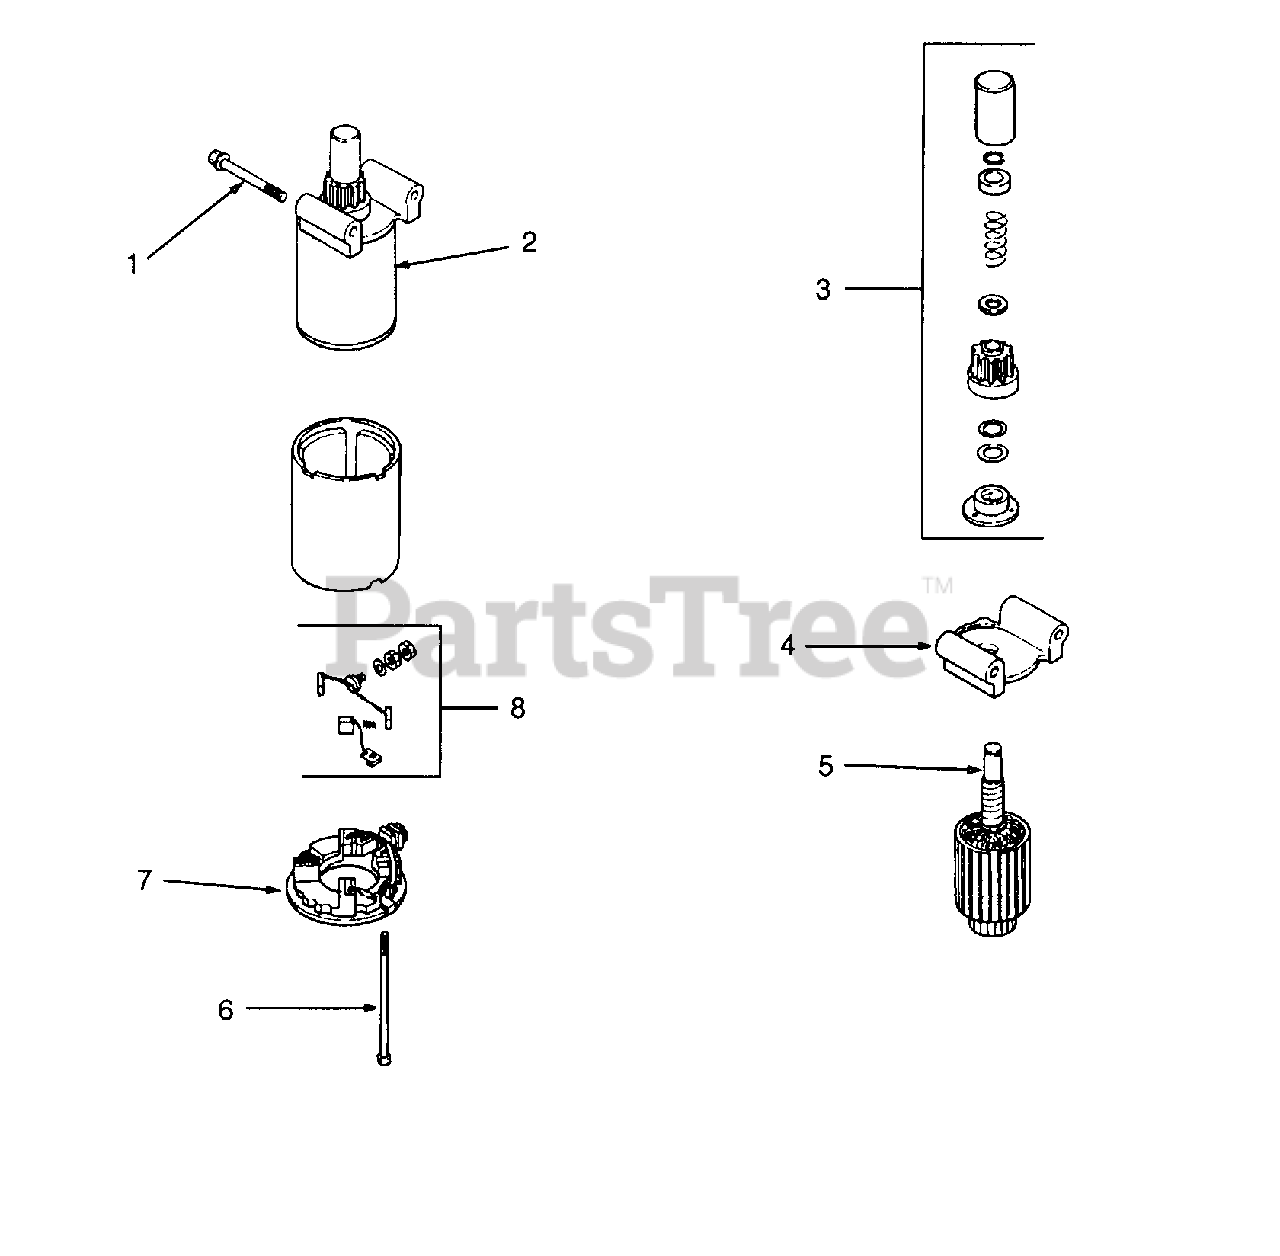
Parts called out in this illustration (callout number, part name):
1	Screw, Hex Flange, M8 x 1.25 x 70
2	Starter Assembly
4	Cap, End
6	Screw, Hex Flange, 1/4 - 20 x 4-5/8
7	Commutator, End Cap
8	Kit, Brush and Spring
